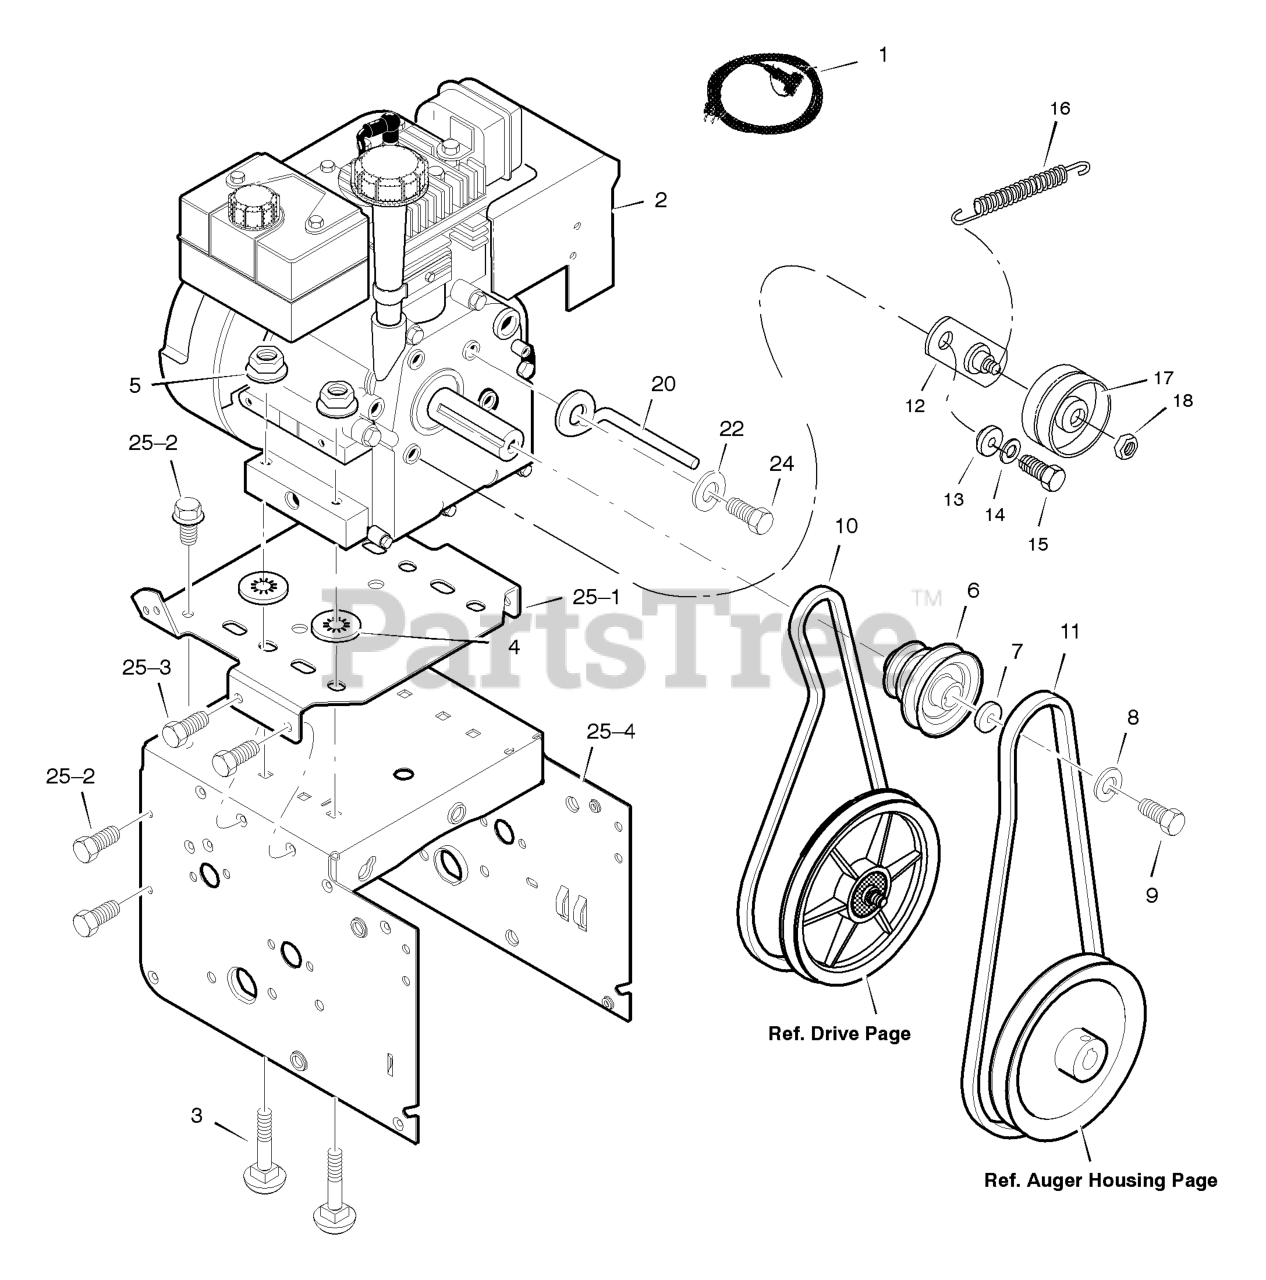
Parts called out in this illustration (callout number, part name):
1	CORD, Electric, 10FT. 110V
2	ENGINE
3	BOLT, CARRIAGE 5/16-18
4	RETAINER, PUSH
5	NUT 5/16-18
6	PULLEY, ENGINE
7	WASHER
8	WASHER, SPLIT .38ID
9	SCREW, 3/8-24 x 1.00
10	BELT, V 3L 33.13LG
11	BELT, V 4L35.6 LG
12	BRACKET ASSEMBLY, IDLER
13	BUSHING, IDLER BRACKET
14	WASHER, SPLIT .31X.58X.08
15	SCREW, 5/16-24 x 0.75
16	SPRING, IDLER TRACTION DRIVE
17	PULLEY, IDLER
18	NUT, JAM 3/8-16
20	GUIDE, ROD BELT
22	WASHER, SPLIT .31X.58X.08
24	SCREW, 5/16-24 x 0.75
25	FRAME ASSEMBLY
25-1	PLATE, ENGINE MOUNT
25-2	SCREW 1/4-20 X .63
25-3	SCREW 5/16-18 X .50
25-4	FRAME, MOTOR BOX
